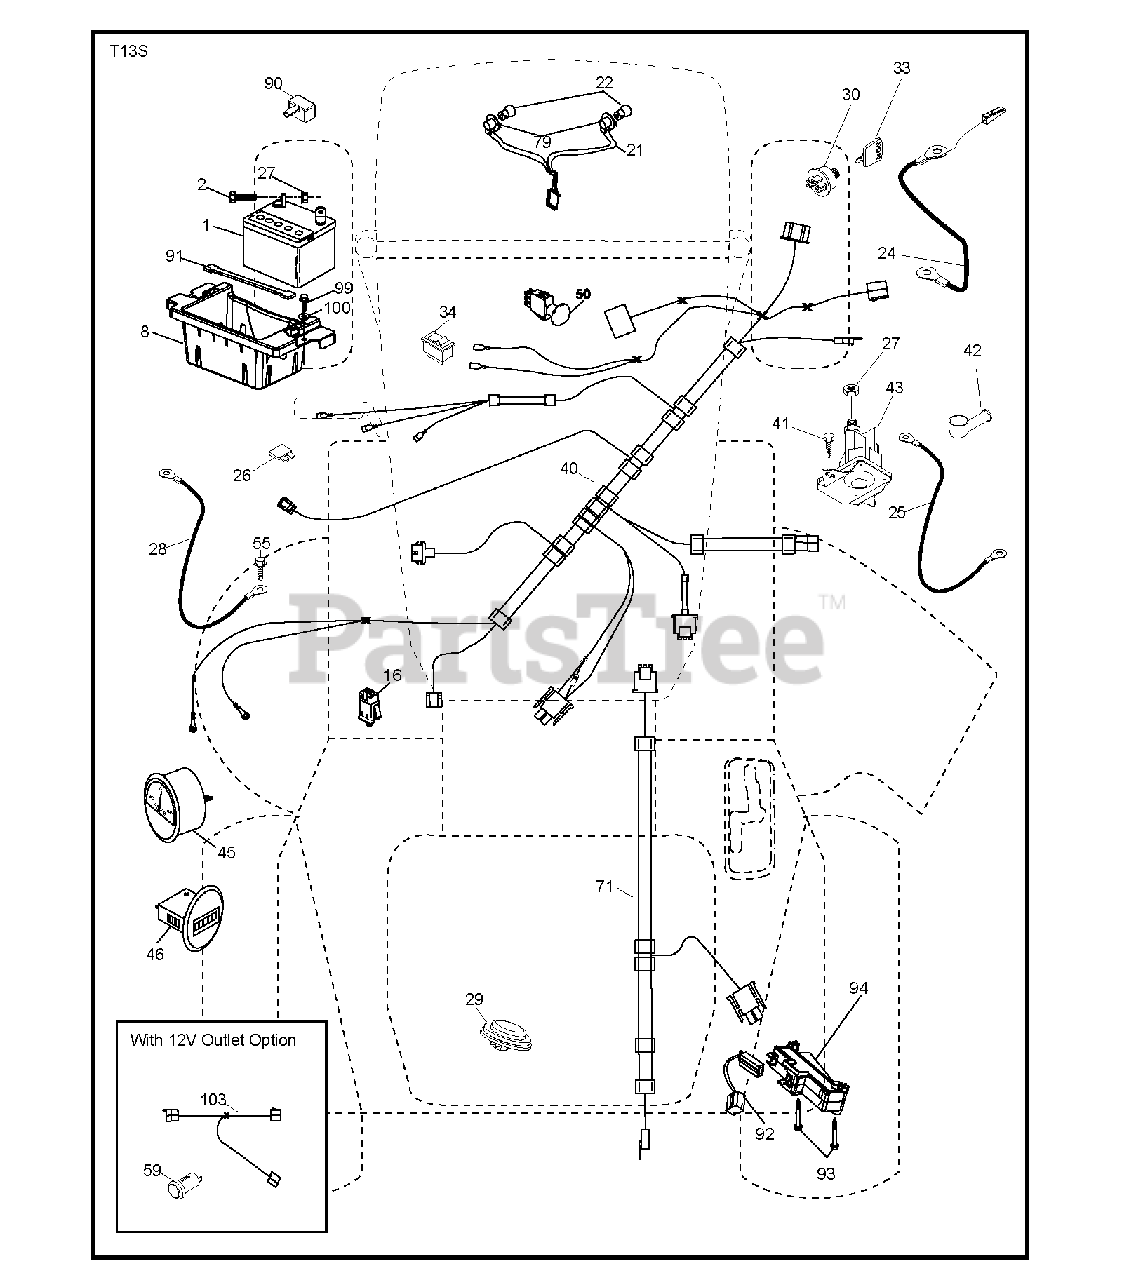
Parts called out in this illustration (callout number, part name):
1	REPL BY 532 12 38-99
8	BOX.BATTERY.MOUNT.FRONT.LT
16	SWITCH INTERLOOK PUSH-IN
21	HARNESS.LIGHT W/4152J BULBS
22	LIGHTBULB
24	CABLE.BATT.POS.WIRE.TG.DA SOL
25	CABLE.STARTER.6G.BL/RED.17.5
26	FUSE 20AMP
27	NUT
28	CABLE GROUND 6 GA 21" 90T BLK
29	SWITCH.SEAT.DELTA.OPC.
30	SWITCH.IGN.DELTA.W.LGH.ROS
33	KEY.CHAIN.BLISTER.PACK.GEN.INT
34	SWITCH LT
40	HARNESS IGN. DASH
41	SCREW
42	TERMINAL COVER
43	SOLENOID.W/BRASS.PLUNG
50	PTO SWITCH
55	SCREW 5/16"
71	HARNESS-CHASSIS SUB
79	BULB HOLDER ASM.
90	COVER.TERMINAL.BATTERY
91	STRAP, BATTERY MOUNT
92	HARNESS.PIGTAIL.CONSLE
93	SCREW.PLASTITE
94	MODULE.REVERSE.ROS
99	SCREW HEXWSHR 1/4-20X3/4
